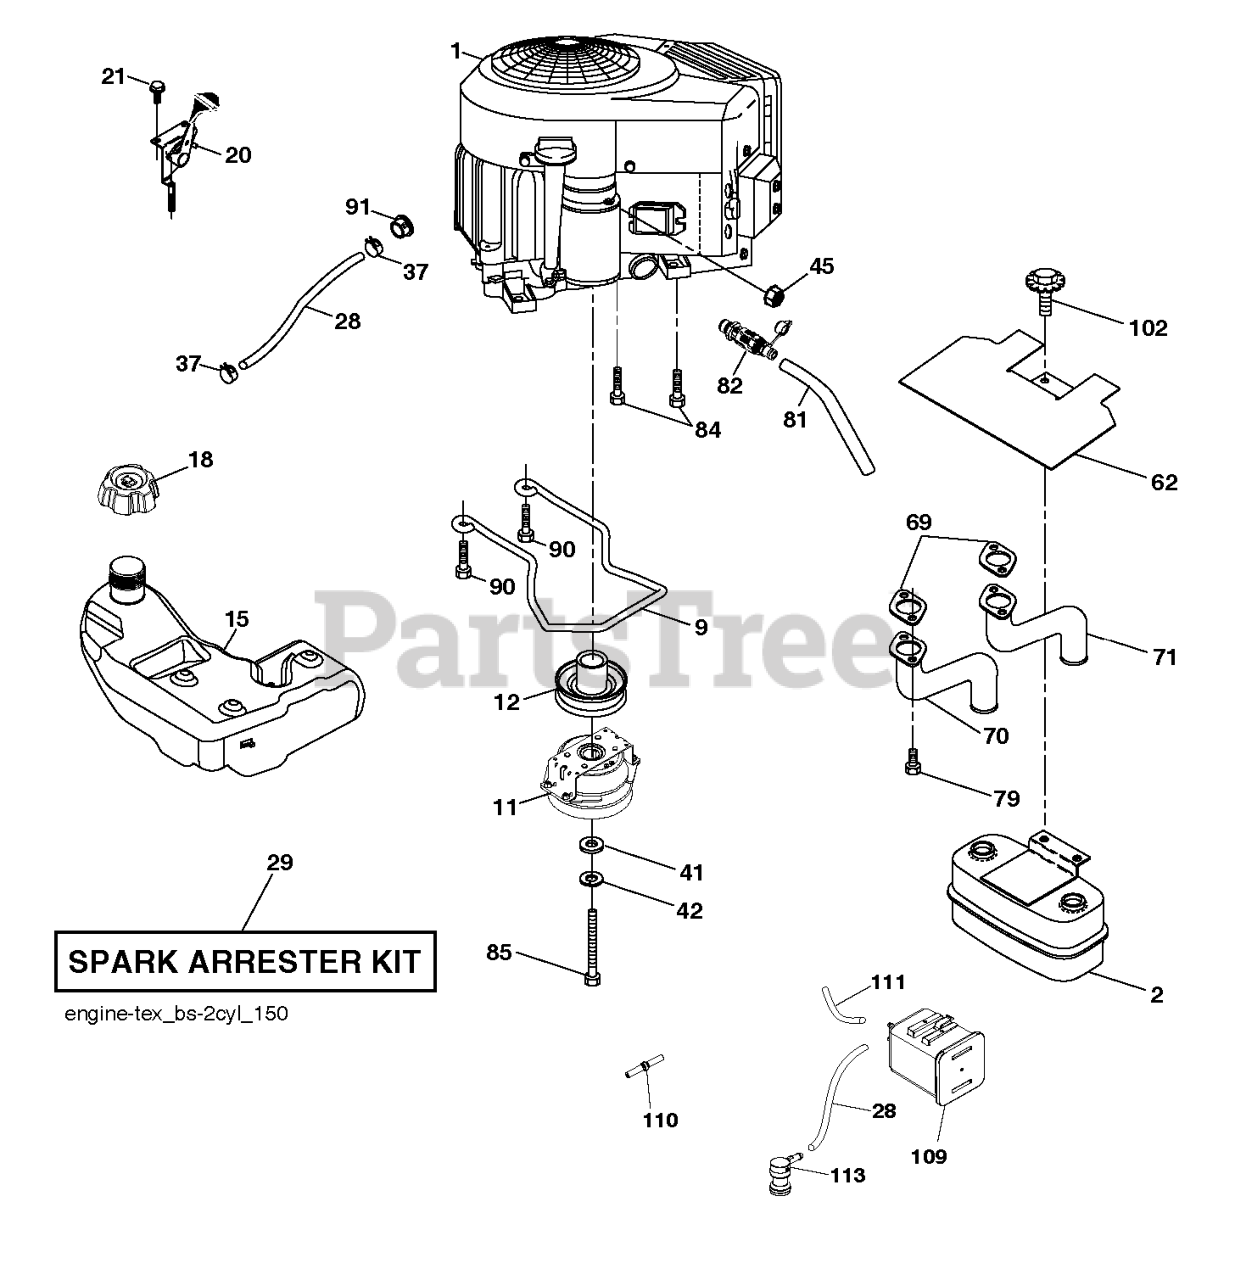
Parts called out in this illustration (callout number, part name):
2	MUFFLER.ASM.TWN.EXTNDED.DFLCTR
9	KEEPER.BELT.ENG.4.25"2.BLT.431
11	CLUTCH.OGURA.4.4PD.GT1.5-EH13V
12	PULLEY.ENGINE.TUFFTORQ
15	TANK.ASM.FUEL.3GA.CARB
18	CAP ASSY FUEL 3" GRAY
20	CONTROL.TH/CK.COBRA.B&S.TWN.BK
21	SCREW.#10 X 0.750.BOS
28	LINE.FUEL.64"REAR.EMIS
29	KIT.SPARK ARRESTOR 794945 B&S
37	HOSE CLAMP
42	LOCKWASHER
45	NUT
62	SHIELD.HEAT.MUFFLER
69	GASKET.MUFFLER
70	EXHAUST.TUBE.LH.BS/TWIN
71	EXHAUST.TUBE.RH.B&S.TWIN.INTEK
79	SCREW.SOCKET.HEAD.5/16-18
81	TUBE, DRAIN OIL ASM.
82	VALUE.OIL.DRAIN
84	SCREW.3/8-16
85	CLUTCH BOLT7/16-20X3.5 GR524HR
90	SCREW 3/8-16X1
91	BUSHING.1.375OD
102	SCREW
109	CANNISTER, CARBON
110	VALVE.ASM.ANTI-SLOSH
111	RP PURGE LINE
113	VALVE.SLANT.CARTRDG.90 DEG.TEX
